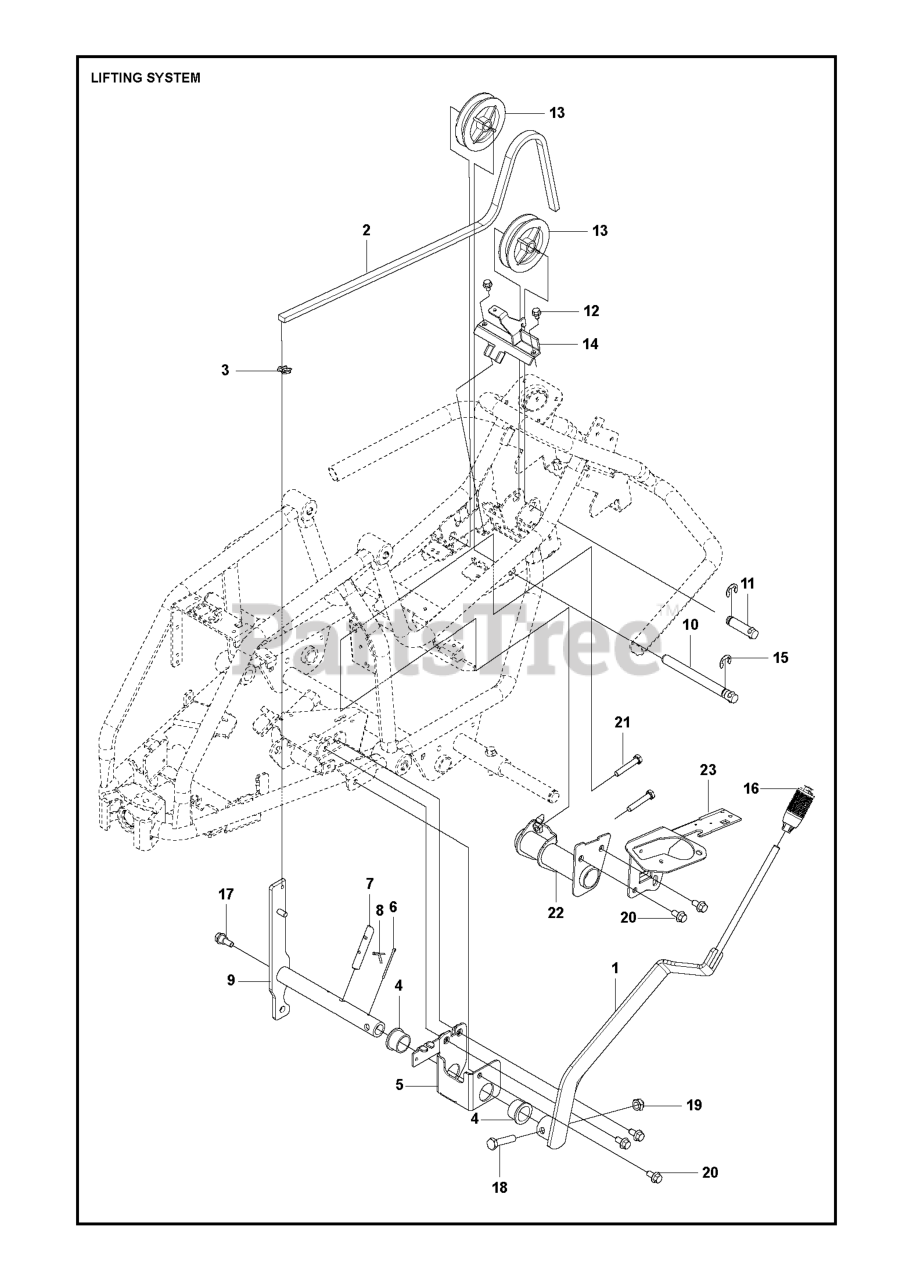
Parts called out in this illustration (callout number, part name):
1	LEVER ASSY
4	BEARING FLANGE
5	BRACKET ASSY
6	COTTER PIN
18	REPL BY 725 25 00-71
21	SCREW
